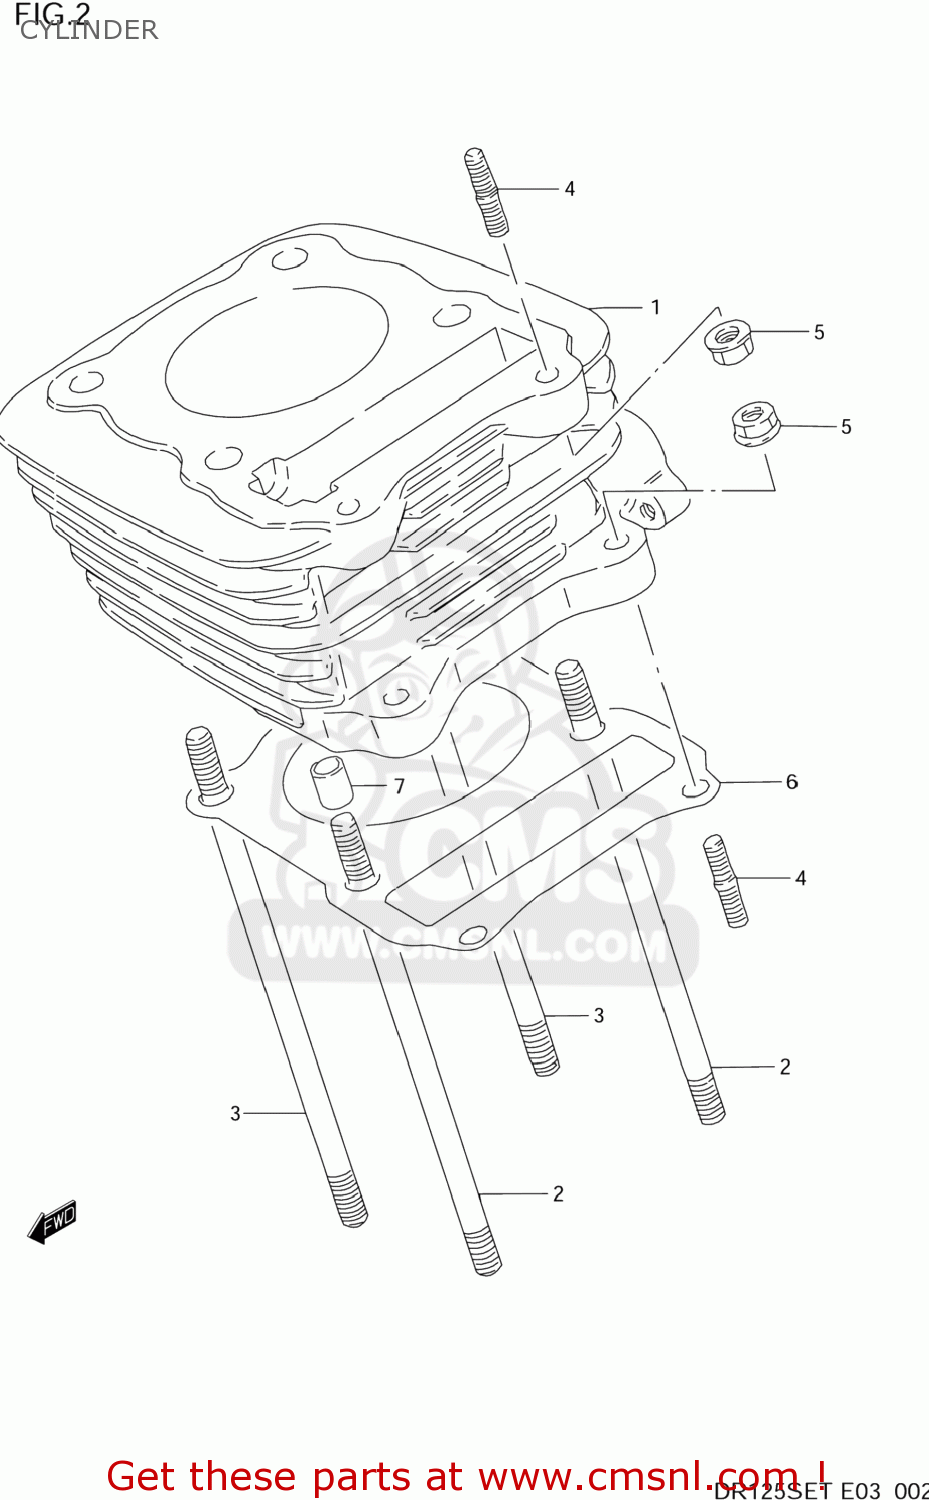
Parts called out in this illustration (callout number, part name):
1	CYLINDER COMP
2	BOLT,STUD
3	BOLT,STUD
4	STUD BOLT
5	NUT
6	GASKET,CYLINDER (NAS)
7	PIN
